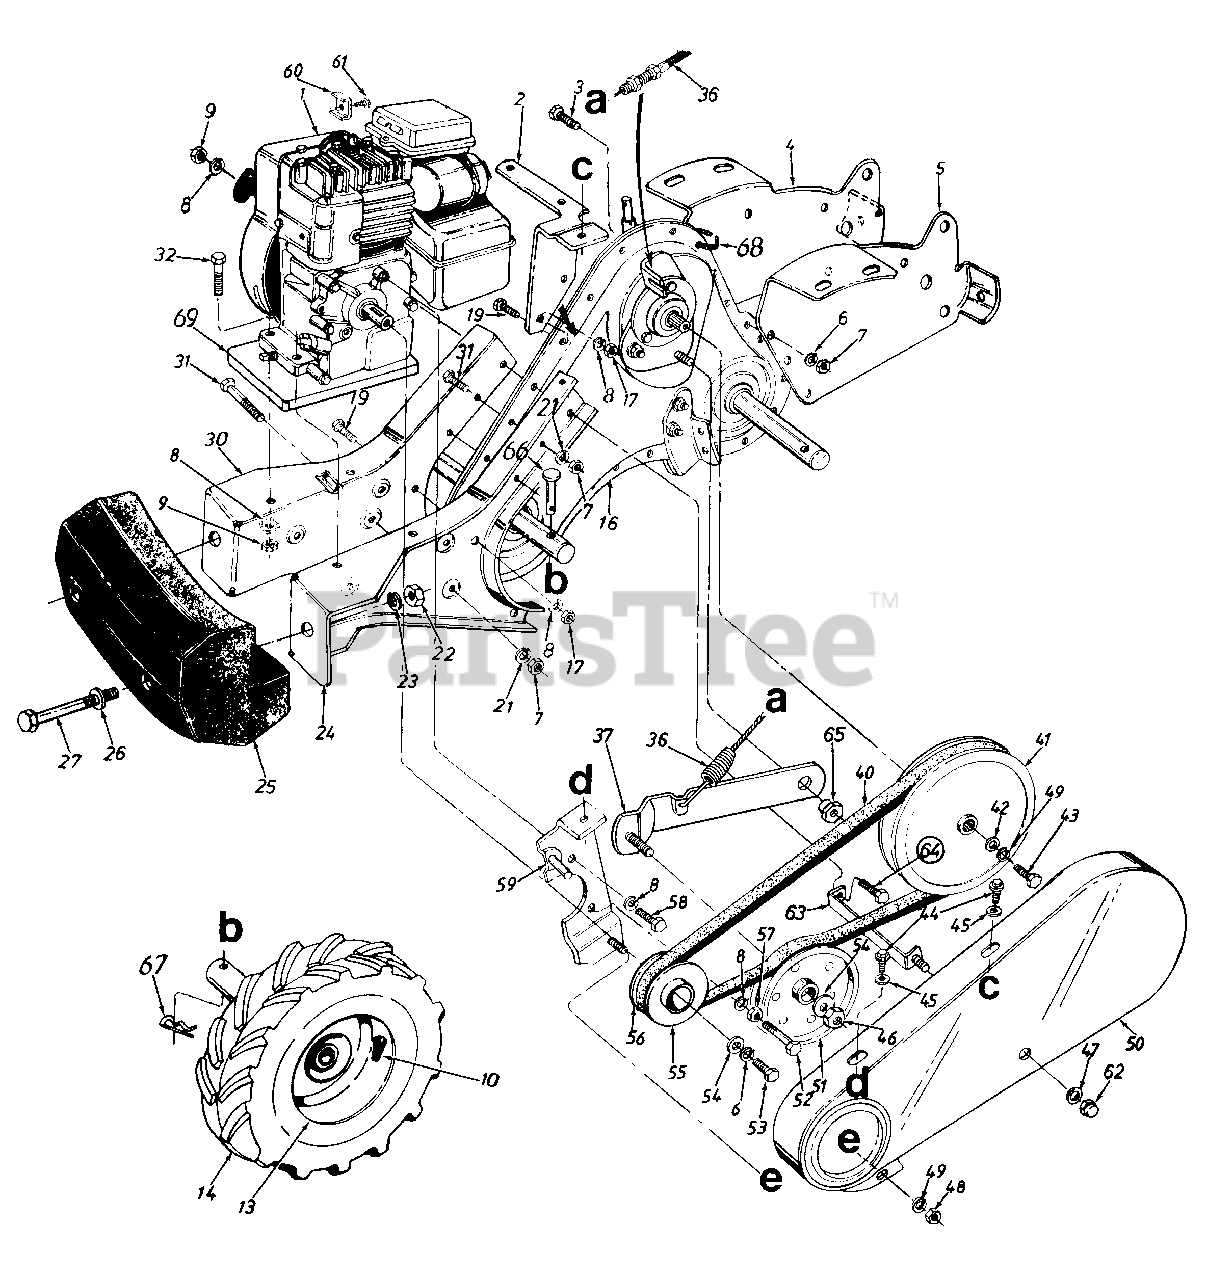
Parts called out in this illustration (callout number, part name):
1	Engine
7	Hex Nut 3/8-16 Thd.
8	L-Wash. 5/16" I.D.
9	Hex Nut 5/16-18" Thd.
10	Air Valve
16	Gear Case Ass'y. Comp.
17	Hex Nut 5/16-18 Thd.
19	Hex Bolt 5/16-18 x .75" Lg.
21	L-Wash. 3/8" I.D.--H.D.
22	Hex Nut 1/2-13 Thd.
23	L-Wash. 1/2" I.D.
26	Fl-Wash. .510" I.D. x 1.0"
27	Hex Bolt 1/2-13 x 5.00" Lg.
32	Hex Bolt 5/16-18 x 2.75"
36	Clutch Control Cable 46" Lg.
37	Idler Bracket Ass'y.
40	"V"-Belt
41	Fl-Pulley 8" O.D.
42	Fl-Wash. 1/4" I.D. x .93" O.D.
43	Hex Bolt 1/4-28 x .75" Lg.
44	Hex Wash. Hd. S-Tap Scr. 1/4-20 x .50" Lg.
45	Fl-Wash. .281" I.D. x .625"
46	Hex Cent. L-Nut 3/8-24 Thd.
47	Fl-Wash. .266" I.D. x .625" O.D.
48	Hex Nut 1/4-20 Thd.
49	L-Wash. 1/4" I.D.
51	Fl-Idler w/Flanges 3.75" O.D.
52	Hex Bolt 5/16-24 x 1.75"
53	Hex Bolt 3/8-24 x 1.00" Lg.
54	Fl-Wash. 3/8" I.D. x 1.00"
55	Outer Engine Pulley Half
56	Inner Engine Pulley Half
57	Hex Nut 5/16-24 Thd.
58	Hex Bolt 5/16-24 x .62" Lg.
59	Belt Keeper Ass'y.
60	Casing Clamp
61	Hex Sems Scr. #10-32 x .62"
62	Hex Cap Nut 1/4-28 Thd.
63	Belt Cover Brkt. Ass'y.
64	Hex Bolt 5/16-18 x 1" Lg. (Gr. 5)
65	Shld. Nut
66	Clevis Pin
67	Hairpin Clip
68	Cable Tie--Self Clinching
69	Engine Spacer Block
